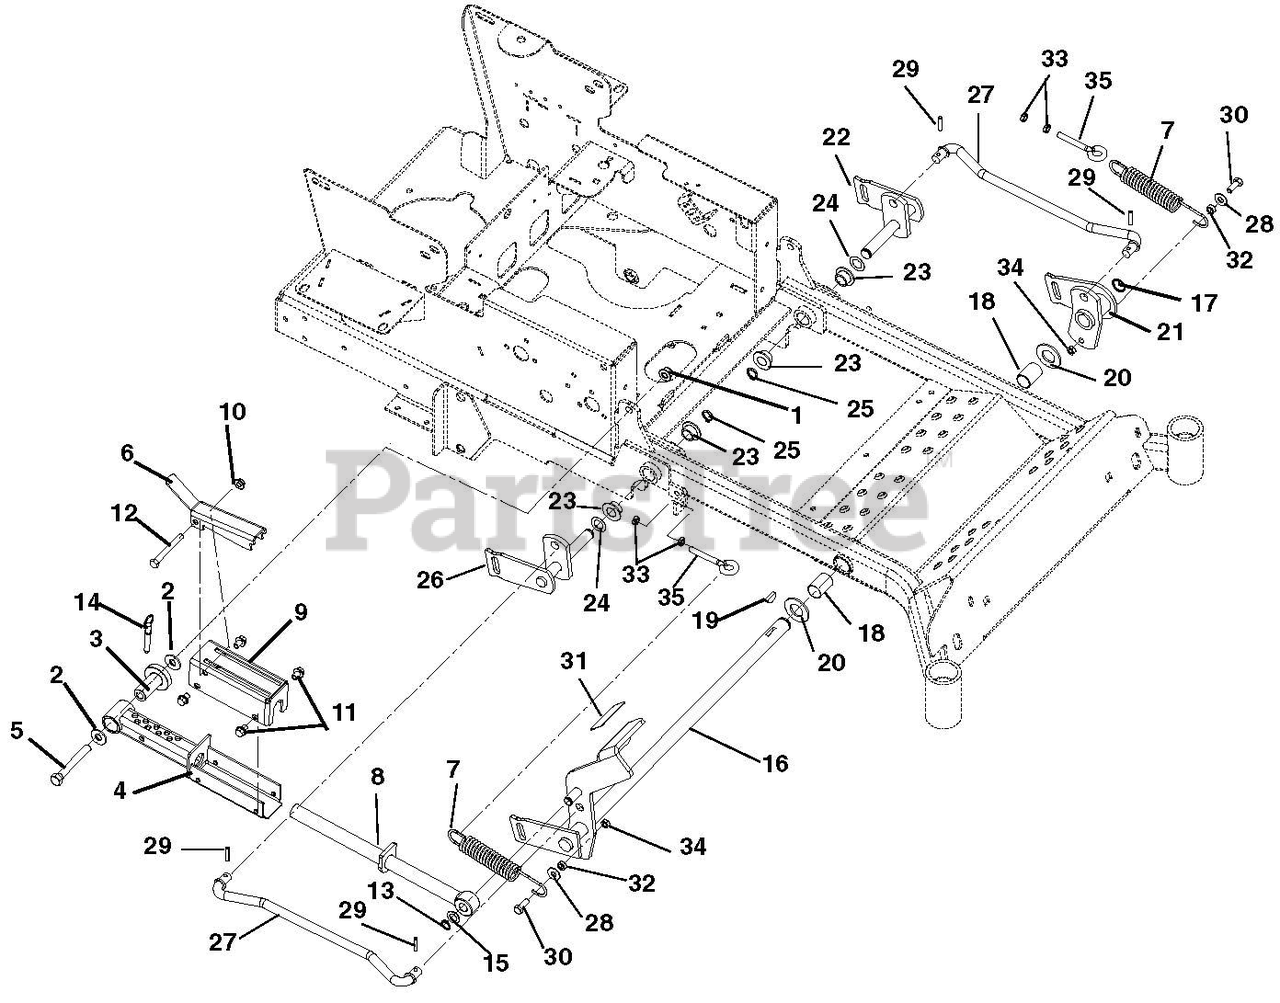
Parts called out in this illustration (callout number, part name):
1	Nut, Locking Top Flange .50-13
2	Washer, Flat Steel .531 x 1.25 x .10
3	Bearing, Pedestal
4	Weldment, Mechanical Lift
5	Bolt, Hex .50-13 x 3.75 Grade 5
6	Lock-Up, Mechanical Lift
7	Spring, Tension .162 x 1.25 x 8.25 Weldment 25
8	Weldment, Mechanical Lift Shaft
9	Weldment, Mechanical Lift Cover
10	Nut, Nyloc Flange 3/8-16
11	Screw, Tapping .38-16 x .50 Hex Washer Head
12	Bolt, Hex .38-16 x 3.25 Grade 5
13	Ring, Retaining External .625 x .050
14	Pin, Spring Ball .375 O.D. x 1.50
15	Washer, Flat Steel .630 x 1.005 x .062
16	Weldment, Foot Operated Deck Lift
17	Ring, Retaining External 1.00 x .078
18	Bushing 1.00 ID x 1.125 OD x 1.50
19	Key, Woodruff .25 x 1.00
20	Washer, Flat Steel 1.062 x 2.0 x .134
21	Weldment, Left Hand Mower Lift Arm
22	Weldment, Left Hand Rear Mower Lift Arm
23	Bushing, Flange Nylon .762 x 1.0 x .580 x 1.48
24	Washer, Hardened Steel .758 x 1.23 x .031
25	Ring, Retaining External .689 x .077
26	Weldment, Right Hand Rear Mower Lift Arm
27	Rod, Lift Assist
28	Washer, Flat Steel .438 x 1.00 x .083
29	Pin, Roll .25 x 1.25 Stainless Steel
30	Bolt, Hex .38-16 x 1.00 Grade 5
31	Grip, Pedal
32	Bushing, Sleeve .377 x .624 x .235
33	Nut, Hex-Jam .375-16
34	Nut, Locking-Jam-Center .375-16
35	Bolt, Eye .375-16 x 2.50
